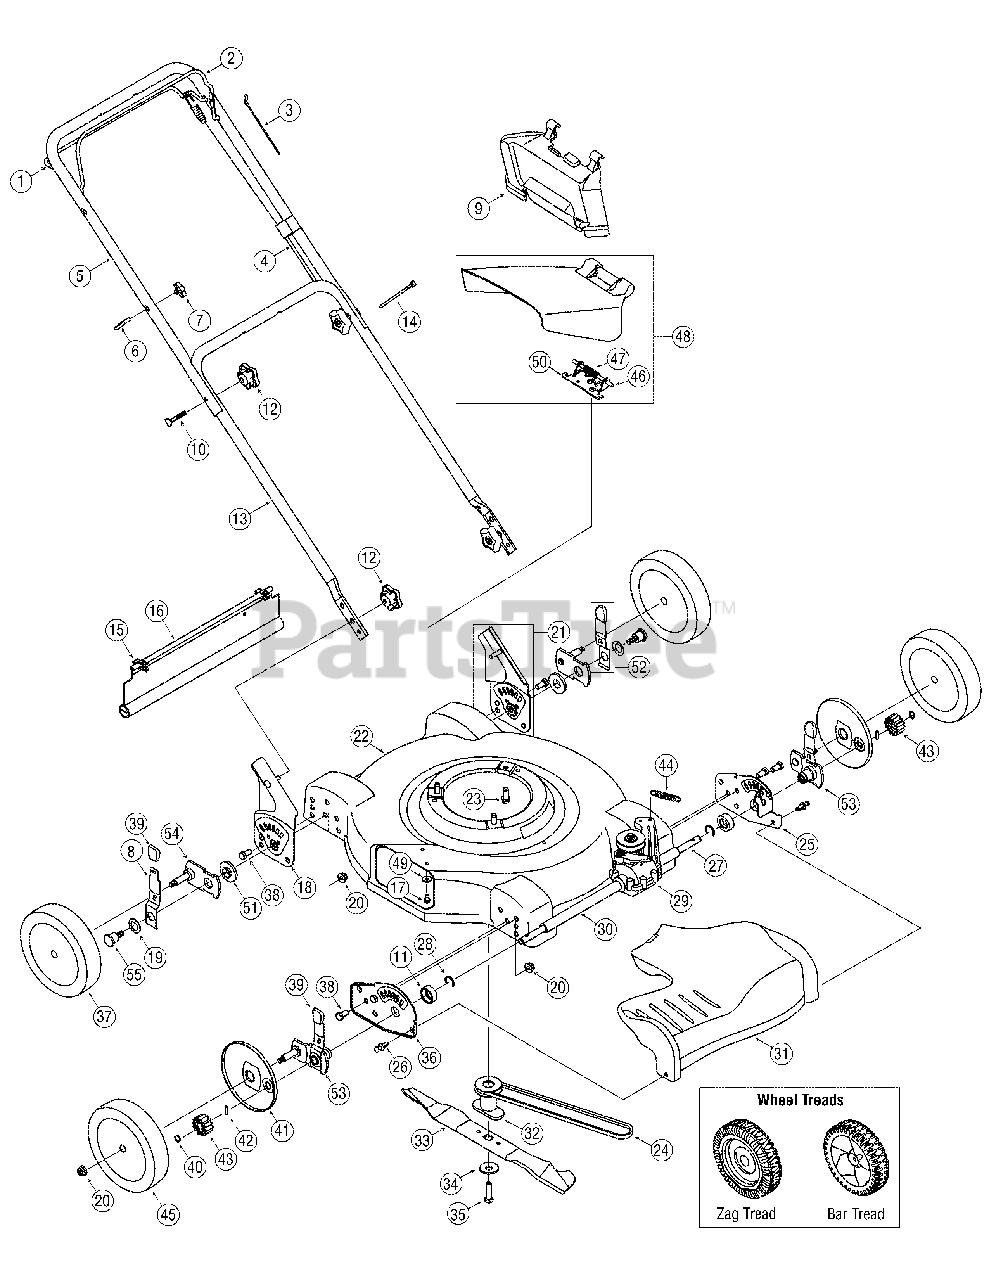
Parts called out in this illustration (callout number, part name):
1	Drive Control
3	Blade Control Cable
4	Drive Control Cable
6	Eye Bolt
7	Wing Nut, 1/4-20
8	Spring Lever
9	Mulching Baffle
10	Carriage Bolt, 5/16-18 x 2.0
11	Bearing Support Spacer
12	Wing Nut
14	Cable Tie
15	Hinge Clip
16	Trail Shield
17	Hex Screw, 1/4-20 x.500
20	Lock Nut, 3/8-16
23	Hex Washer Scr., 3/8-16 x 1.0
24	V-Belt, 3L x 32.90
26	Rivet
27	Sleeve Spacer, .550 ID x 2.22
28	Retainer Ring
29	Transmission Assy. Comp.
30	Sleeve Spacer, .550 ID x 8.51
31	Transmission Cover
32	Blade Adapter
33	22" Mulching Blade
34	Washer, Bell, .396 x 1.140 x .095
35	Hex Cap Screw, 3/8-24 x 1.5
37	Rear Wheel, 8 x 1.8, Bar
38	Hex Cap Screw, 3/8-16 x.75
39	Adjustment Knob
40	Screw 1/4-20 X .39
41	Wheel Dust Cover
42	Pin
43	Spur Gear 14T - RH
43	Spur Gear 14T - LH
44	Ext. Spring, .47 OD x 2.50
45	Front Wheel, 8 x 1.8, Bar
46	Hinge Pin
47	Torsion Spring
48	Side Discharge Assembly
49	Bell Washer, .265 ID x.75 OD
50	Deflector Chute Adapter
51	Height Adjustment Bearing
52	Rear Hgt. Adj. Lever Assembly
53	Front Lever Assembly
54	Rear Pivot Arm Assembly
55	Shoulder Screw, 3/8-16
